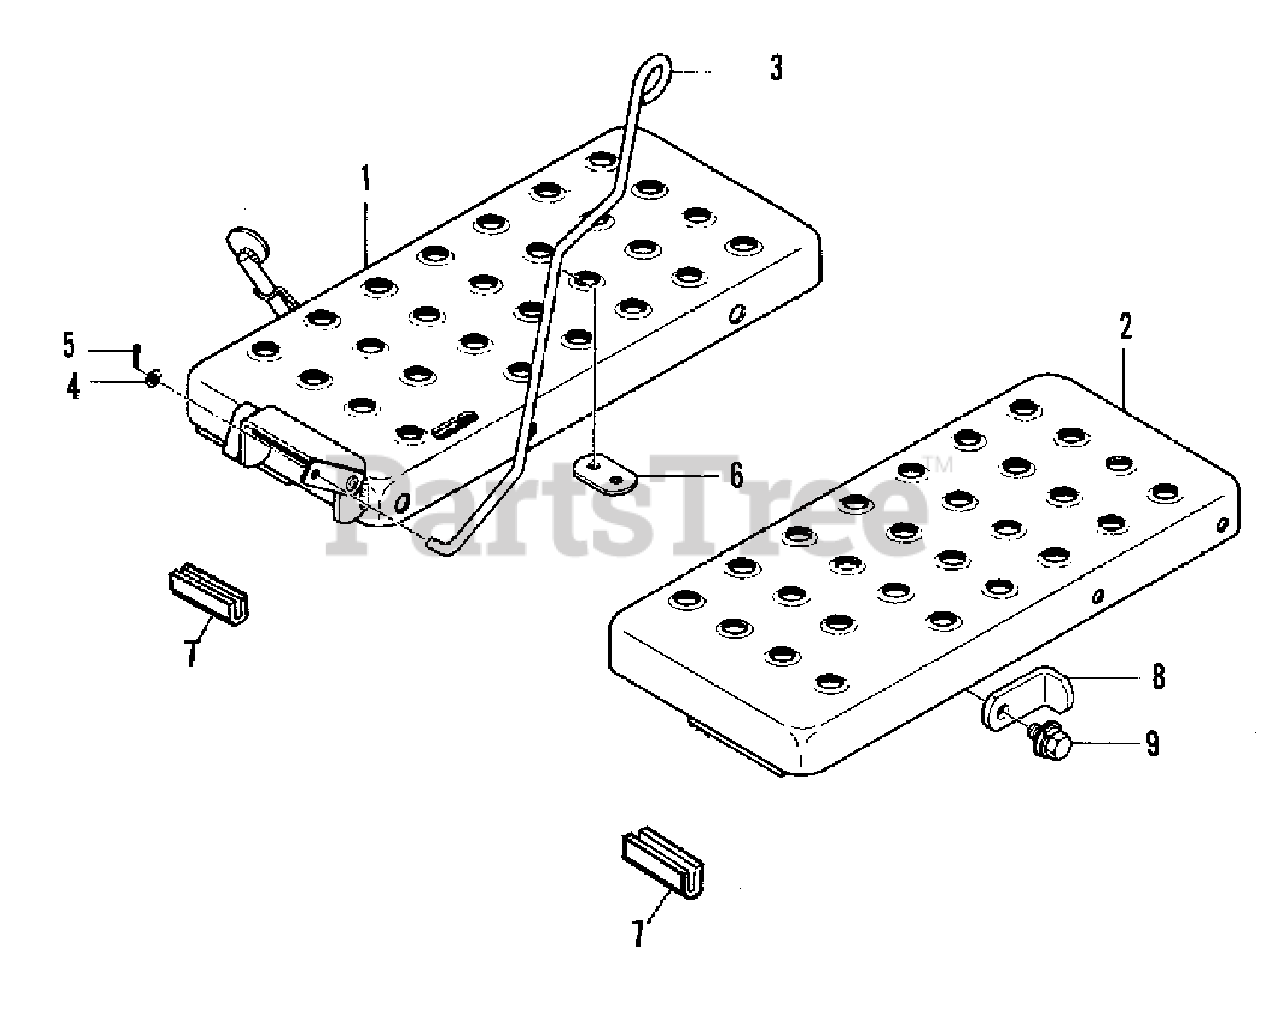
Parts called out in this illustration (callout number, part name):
1	PLATFORM, R.H.
2	PLATFORM, L.H.
3	ROD, control
4	WASHER, M6
5	PIN, cotter
9	CAPSCREW, M10 x 20
